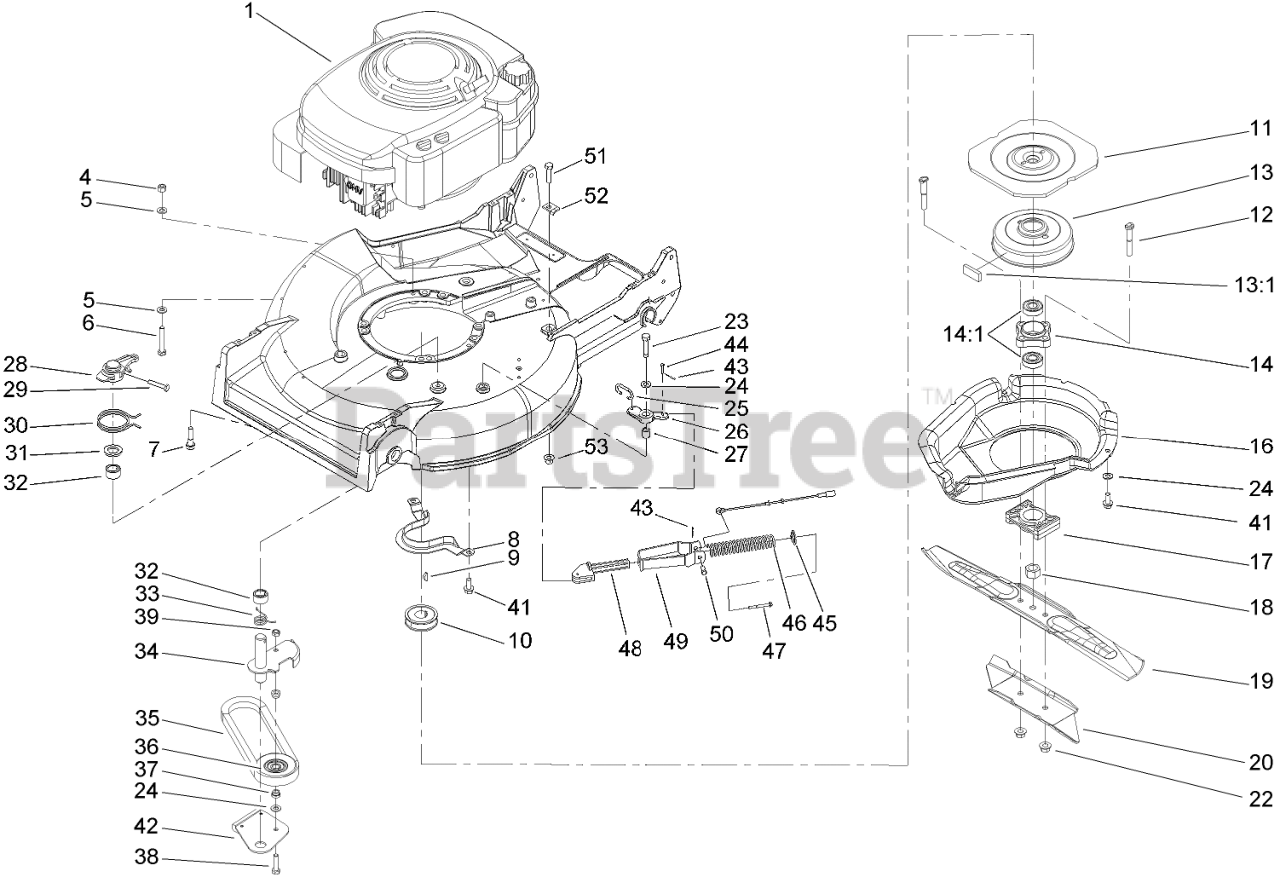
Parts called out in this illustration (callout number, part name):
4	NUT-LOCK, NI
5	WASHER-PLAIN
6	SCREW-HH
7	SCREW-SHOULDER
8	BRACKET-GUIDE, BELT
9	KEY-WOODRUFF
10	PULLEY-DRIVER
11	FLYWHEEL-BBC
12	BOLT-BLADE
13	BRAKE DRUM ASM
13:1	DAMPENER-VIBRATION
14	HUB ASM
14:1	BEARING-BALL
16	SHIELD
17	SPACER-BLADE
18	NUT-BLADE
19	Blade
20	STIFFENER-BLADE
22	NUT-LOCK
23	SCREW-HH
24	WASHER-PLAIN
25	LINK-CONTROL
26	BELLCRANK
27	SLEEVE-BELLCRANK
28	LEVER
29	SCREW-HH
30	SPRING-TORSION
31	WASHER
32	BEARING
33	SPRING-TORSION
34	ARM-IDLER
35	V-BELT
36	PULLEY-IDLER
37	SPACER-PULLEY, IDLER
38	SCREW-HH
39	NUT-LOCK, NI
41	SCREW-HWHTF
42	BRAKE PLATE ASM
43	PIN-COTTER
44	PIN-SPRING
45	RETAINER-SPRING
46	SPRING
47	SCREW-HWHTF
48	GUIDE-SPRING
49	BRACKET-SPRING
50	PIN-CABLE
51	SCREW-HH
52	CLAMP-CABLE
53	NUT-LOCK, NI
